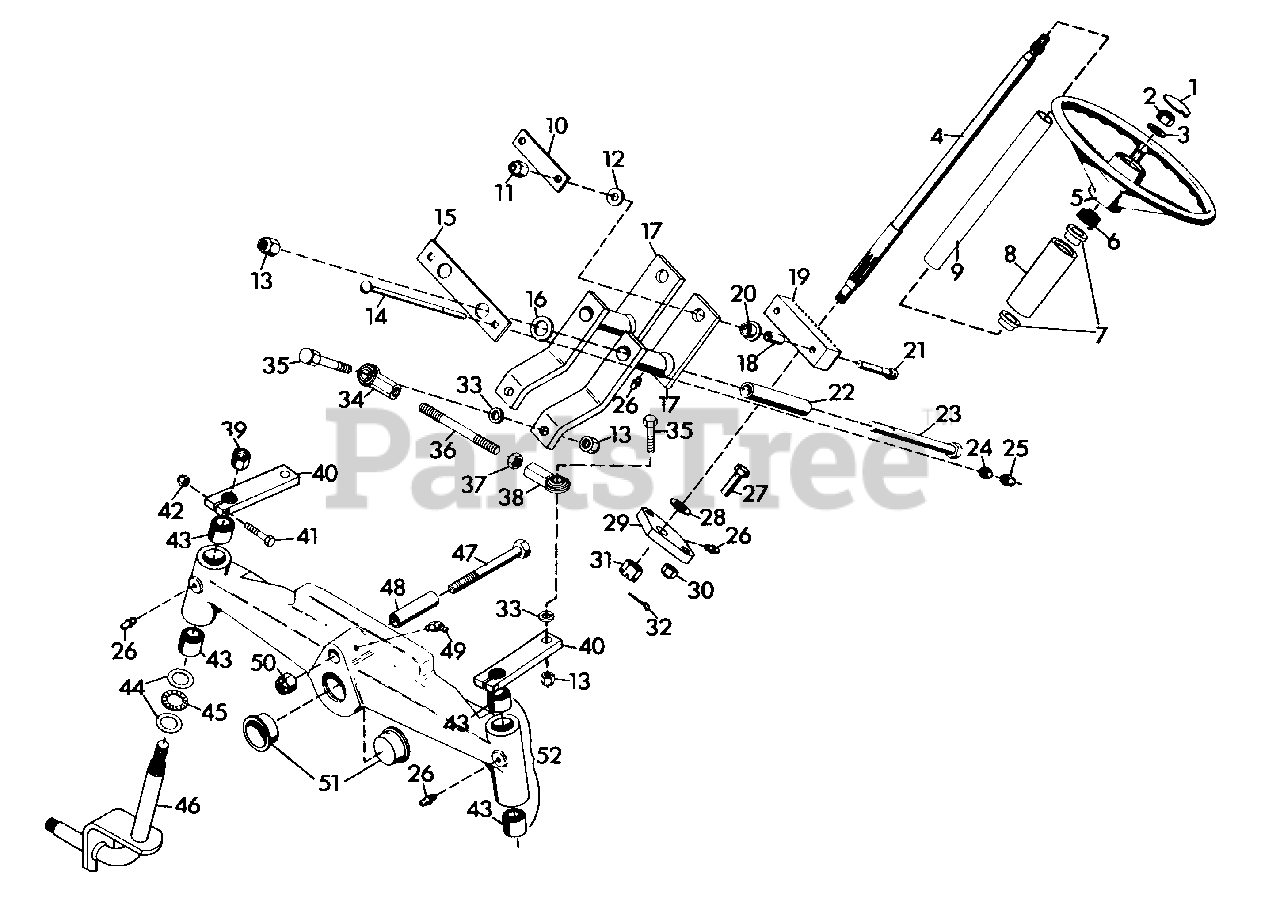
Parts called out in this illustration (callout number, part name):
1	CAP, STEERING WHEEL
2	NUT, JAM 5/8-11 HEX
3	WASHER, FLAT .656X1.312X.095
4	SHAFT, STEERING
5	WHEEL, STEERING
6	SPRING, COMPRESSION 1X.80X36 LB/IN
7	BUSHING, NYLON .760X1.000X.600 FLANGE
8	BUSHING, STEERING WHEEL
9	TUBE, PLASTIC 1.0 I.D.
10	STRAP, RACK AND PINION
11	NUT, LOCK 3/8-16
12	WASHER, FLAT .375X1.125X.065
13	NUT, LOCK 1/2-13
14	BOLT, 5/16-18X5.5 RD HD SQ NK
15	PLATE, ADJUSTMENT
16	RACE, BEARING THRUST .752X1.240X.095
17	WELDMENT, STEERING ARM
18	BUSHING, .391X.622X.670
19	GEAR, RACK
20	BEARING, FLANGE(P/M BRONZE)
21	SCREW, CAP 3/8-16X2.0 HEX SOCKET HD
22	SLEEVE, PIVOT
23	BOLT, HEX 1/2-13X6.0
24	NUT, HEX 5/16-18
25	NUT, LOCK 5/16-18
26	FITTING, LUBE 1/4-28
27	BOLT, HEX 7/16-14X1.5
28	RACE, THRUST
29	SUPPORT, STEERING SHAFT
30	NUT, LOCK 7/16-14
31	NUT, HEX 1/2-13 SLOTTED
32	PIN, COTTER .09X1.00
33	WASHER, LOCK 1/2 REG.
34	ROD END, STEERING L.H.
35	BOLT, HEX 1/2-13X2.00
36	TIE ROD, STEERING
37	NUT, JAM 1/2-20
38	ROD END, STEERING R.H.
39	NUT, HEX 5/8-11
40	ARM, TIE ROD AXLE
41	BOLT, HEX 5/16-24X1.75
42	NUT, LOCK 5/16-24
43	BUSHING, .877X1.004X1.0
44	RACE, BEARING THRUST
45	BEARING, NEEDLE THRUST
46	WELDMENT, KING PIN
47	BOLT, HEX 3/4-10X4.5
48	TUBE, AXLE PIVOT
49	FITTING, LUBE 45 DEG.
50	NUT, LOCK 3/4-10
51	CAP, FRONT AXLE
52	AXLE, STEERING
